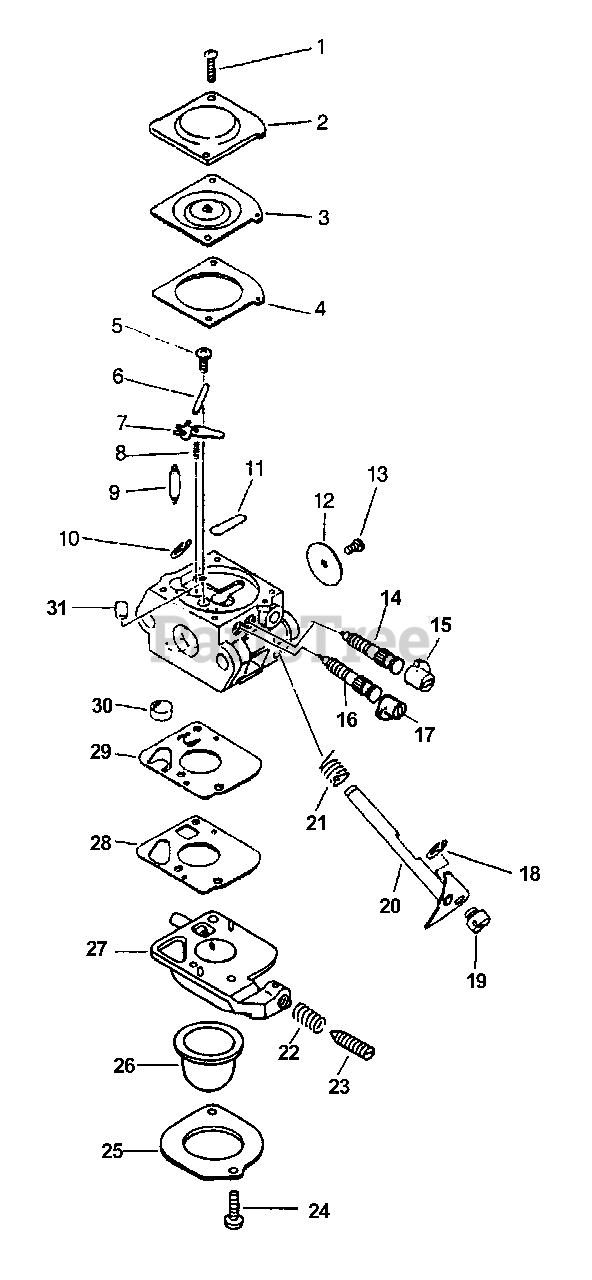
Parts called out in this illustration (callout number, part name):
2	COVER, METERING DIAPHRAGM
3	DIAPHRAGM, METERING
4	GASKET, METERING
6	PIN, METERING LEVER
7	LEVER, METERING
8	SPRING, METERING LEVER
9	VALVE, NEEDLE
11	PLUG, WELCH
12	VALVE, THROTTLE
14	NEEDLE, MIXTURE
15	CAP, LIMITER - WHITE
16	NEEDLE, HIGH SPEED
17	CAP, LIMITER - RED
20	SHAFT, THROTTLE
21	SPRING, THROTTLE RETURN
23	SCREW, THROTTLE ADJUST
25	RETAINER
26	BULB, PURGE
27	BODY ASSY, PURGE
28	GASKET, PUMP
29	DIAPHRAGM, PUMP
30	STRAINER
31	NOZZLE, CHECK VALVE
